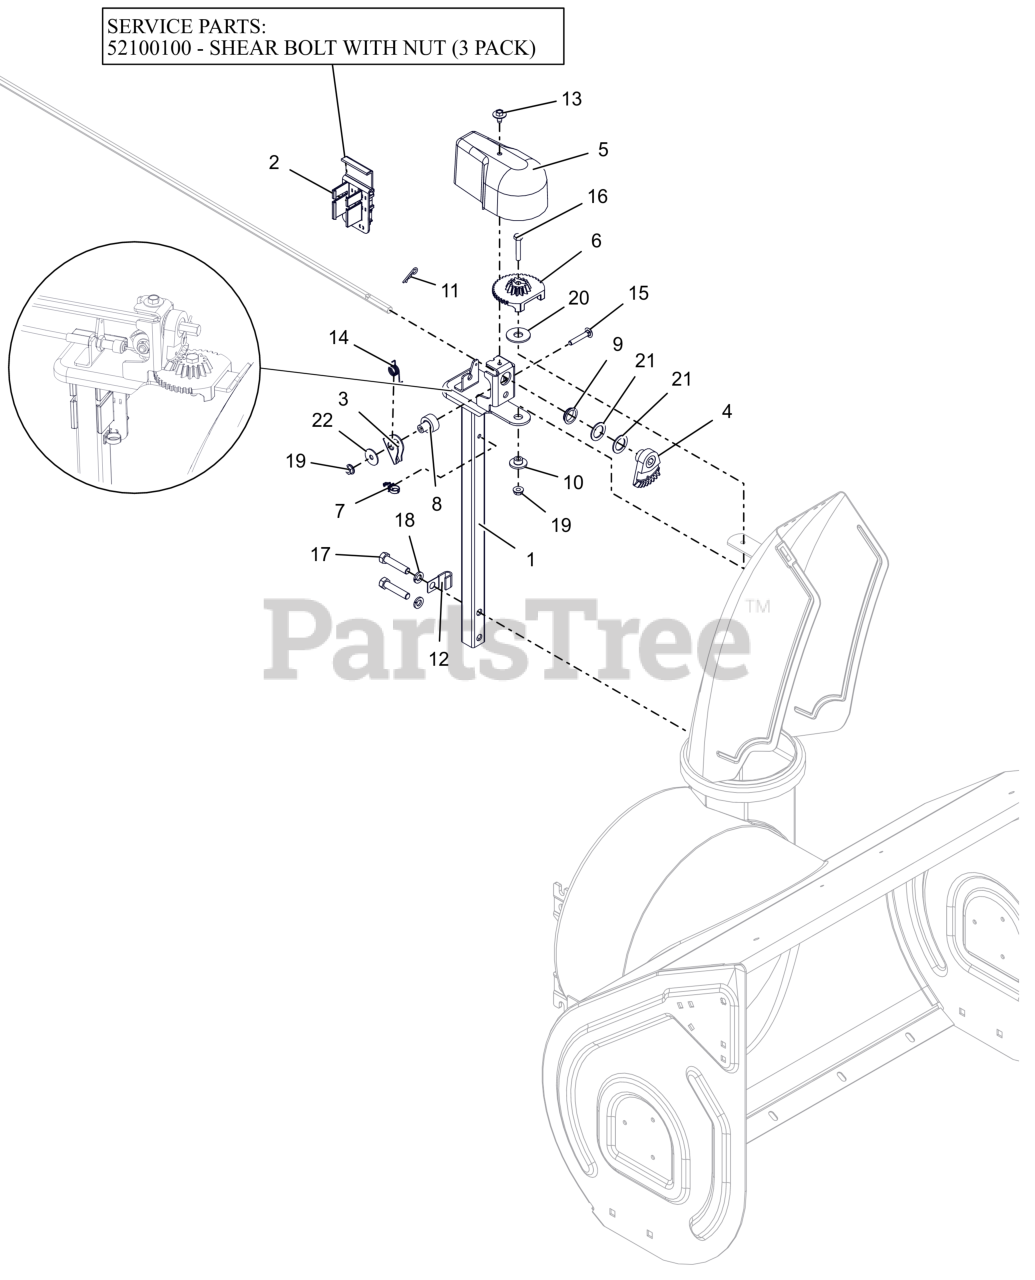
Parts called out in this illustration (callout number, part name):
1	PEDESTAL, CHUTE - QUICK STICK
2	HOLDER W LARGE SHEAR BOLT /NUT
2	SHEAR BOLT SERVICE ASSEMBLY
3	ARM, LOCKING
4	GEAR, CHUTE-ACTUATION
5	COVER, CHUTE GEAR
6	GEAR, CHUTE
7	CLIP, CABLE GUIDE
8	BUSHING, LOCK ARM
9	BUSHING, POLYLINER-.75 SNAPIN
10	BSHG-FLG .265X.477X.375X1.00
11	PIN, HAIR #213 .08X1.19 ZCC
12	J-CLAMP
13	SCR, TAP .25-20X.50 LG HWH ZCC
14	SG-TORS
15	BLT, RHSN .25-20X1.50 G5 ZCC
16	BLT, HEX .25-20X1.50 G5 ZCC
17	BLT, HEX .38-16X1.75 G5 ZCC
18	WSHR,LK-REG .375X.094 ZCC
19	NUT-LK-CTR-FLG .25-20 ZC120
20	WSHR-FLT-NYL .515X1.375X.093
21	WSHR, FLT .754X1.125X.062 ZCC
22	WSHR,FLT .281X1.000X.063 ZCC
